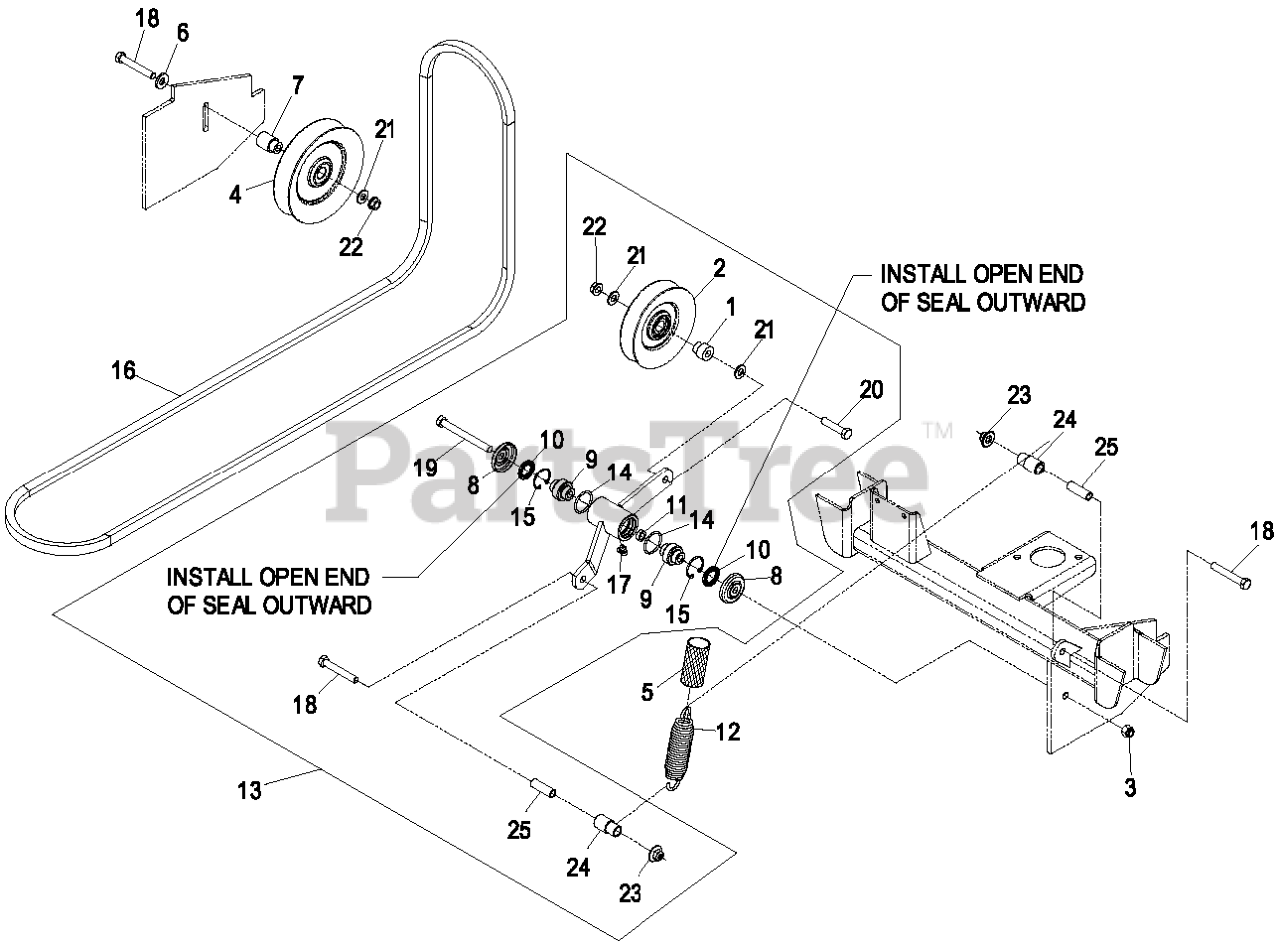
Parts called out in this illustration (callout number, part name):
1	BUSHING-IDLER
2	PULLEY-IDLER
3	NUT-LOCK, NI
4	PULLEY-IDLER
5	DAMPENER,SPRING
6	WASHER-BELLEVILLE
7	BUSHING-IDLER
8	GUARD-TOP
9	BEARING-SPHERICAL
10	SEAL-LIP, SINGLE
15	RING-SNAP
16	BELT,B 123.2
17	FITTING-GREASE, 90 DEG
18	BOLT-CARR
19	SCREW-HH
20	SCREW-HH
21	WASHER-FLAT
22	NUT-HHF, WHIZ
23	NUT-HF, NI
24	BUSHING,PLASTIC
